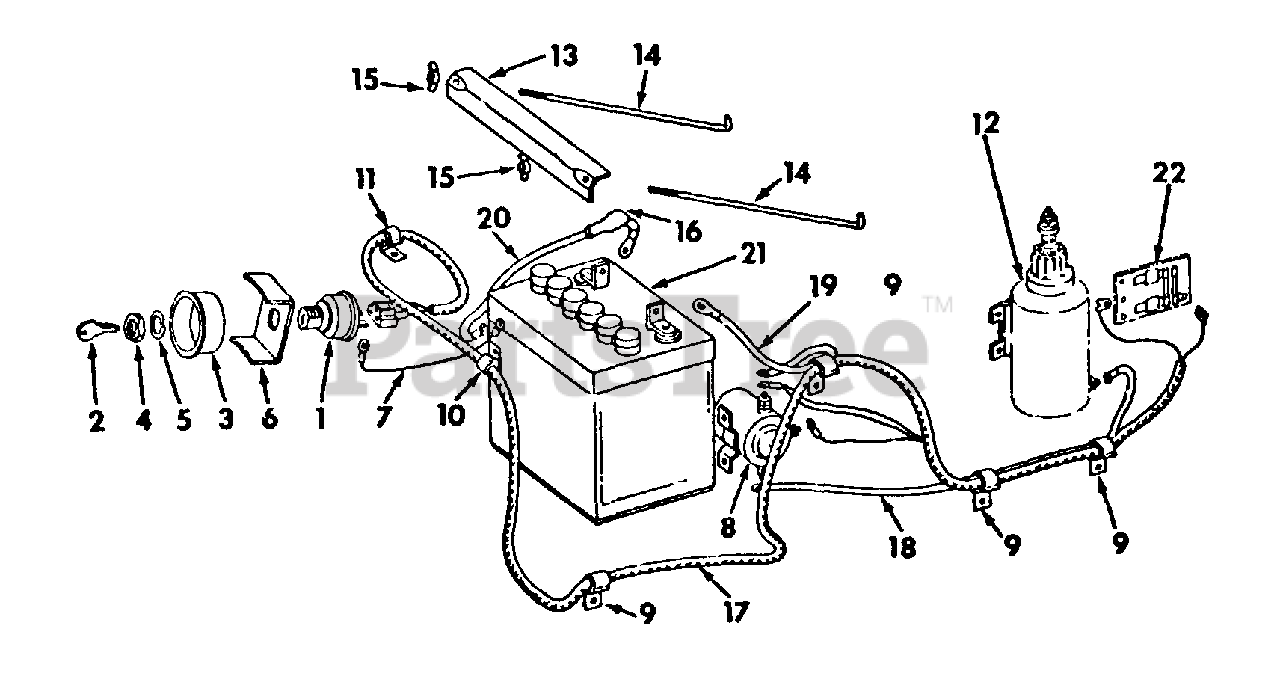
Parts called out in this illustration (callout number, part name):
1	SWITCH, MAGNETO IGNITION AND STARTING
2	KEY, IGNITION SWITCH
3	SOCKET, IGNITION SWITCH
4	NUT, MAGNETO IGNITION KEY MOUNTING
5	WASHER, MAGNETO IGNITION KEY MOUNTING
6	RETAINER, IGNITION SWITCH
7	CABLE ASSY, SWITCH TO GROUND
8	SWITCH, MAGNETIC - DELCO REMY
11	CLIP, CABLE HARNESS
12	MOTOR, STARTING
13	CLAMP, BATTERY HOLD DOWN
14	BOLT, BATTERY HOLD DOWN
15	NUT, 1/4-20 WING
16	COVER, BATTERY TERMINAL
17	HARNESS ASSY, CABLE
18	CABLE ASSY, MAGNETIC SWITCH TO MOTOR
19	CABLE ASSY, BATTERY
20	CABLE ASSY, GROUND
21	BATTERY, LOW-MAINTENANCE 12 VOLT
22	PANEL, RECTIFIER
